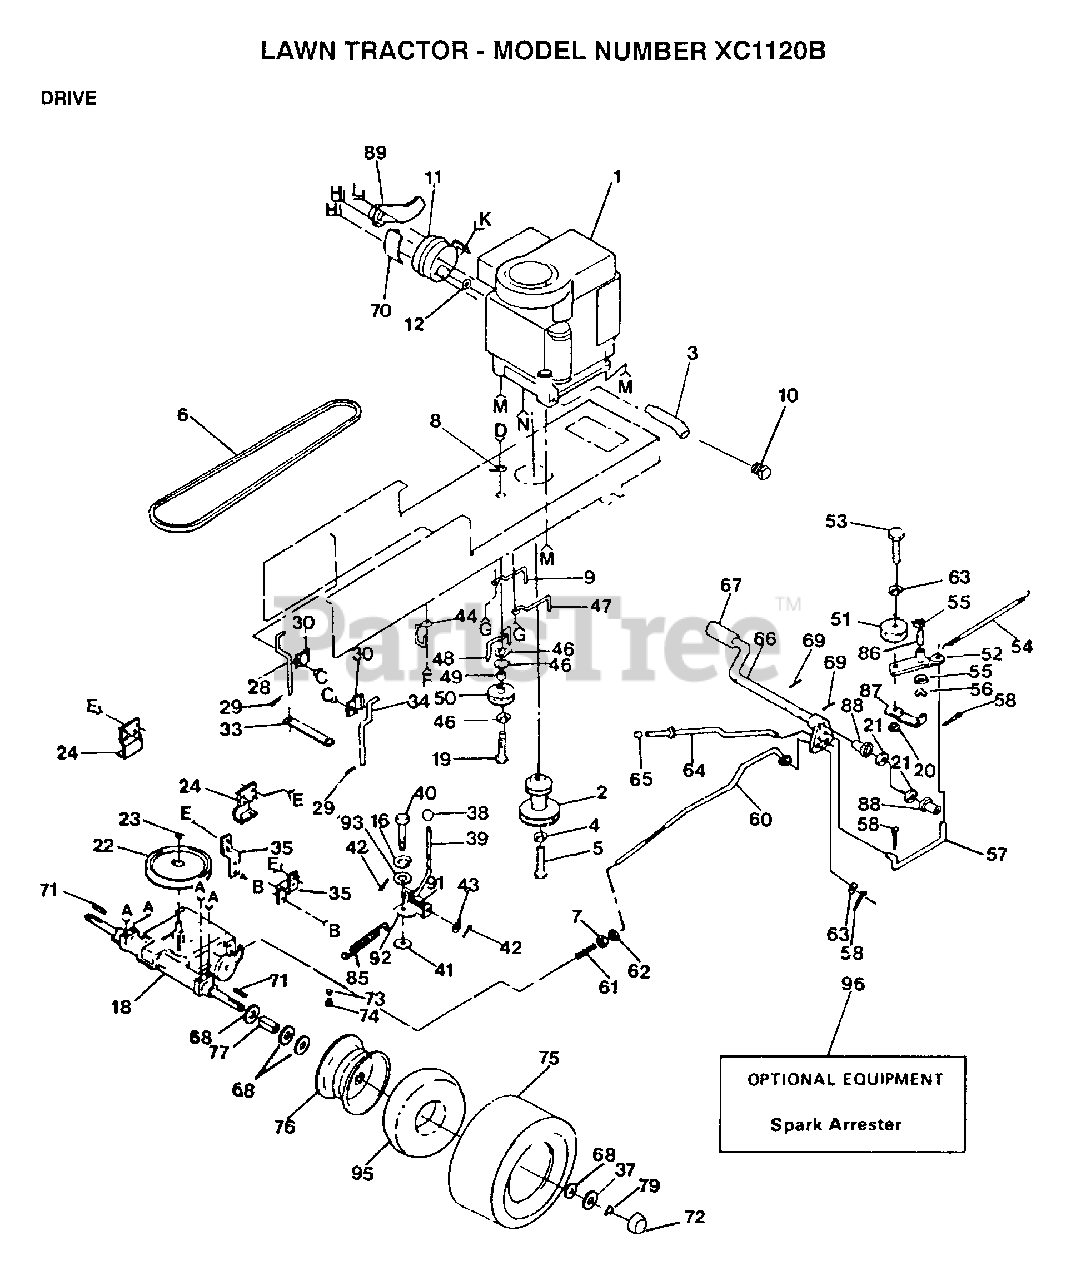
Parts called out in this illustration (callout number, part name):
1	ENGINE BRIGGS AND STRATTON
4	LOCKWASHER
5	BOLT
6	BELT-V.90.0.GD.DR
7	NUT
8	CLIP T
9	KEEPER BELT ENGLH
16	LOCKWASHER
19	BOLT
21	WASHER LT
22	PULLEY TRANS
24	BRACKET LT
28	KEEPER BELT LH
29	SPRING.RETAINER
30	CLAMP LT
33	STRAP LOCATOR
34	KEEPER BELTRH
35	STRAP TORQUE
41	WASH-SHFT PLT LT
42	PIN COTTER 1/8
43	WASHER
46	WASHER
47	"KEEPER,BLT ENG LT"
48	BELT KEEPER LT
49	SPACER T
50	PULLEY.IDLER.FLAT
52	ARM IDLER
54	"SPRING, RETURN LT"
55	WASHER LT
56	KLIP RING
57	"LINK, CLUTCH T"
58	COTTER PIN
60	BRAKE ROD LT
61	SPRING ROD LT
62	NUT
63	WASHER
65	PLUNGER CAP T
67	PEDAL COVER T
68	WASHER
70	SHIELD HEAT LTV
72	HUB CAP
73	VALVE CAP
74	VALVE STEM LT
75	TIRE.TS2.18X8.5
76	RIM
77	SPACER LT
79	E-RING LT
86	BOLT
86	"LY, BEARING"
87	RETAIN BELT
88	NYLON BEARING
89	DEFLECTOR MUFFLER
91	SPRING LT
92	PLATE SHIFT LT
93	WASHER LT
95	TUBE.18X9.5-8
